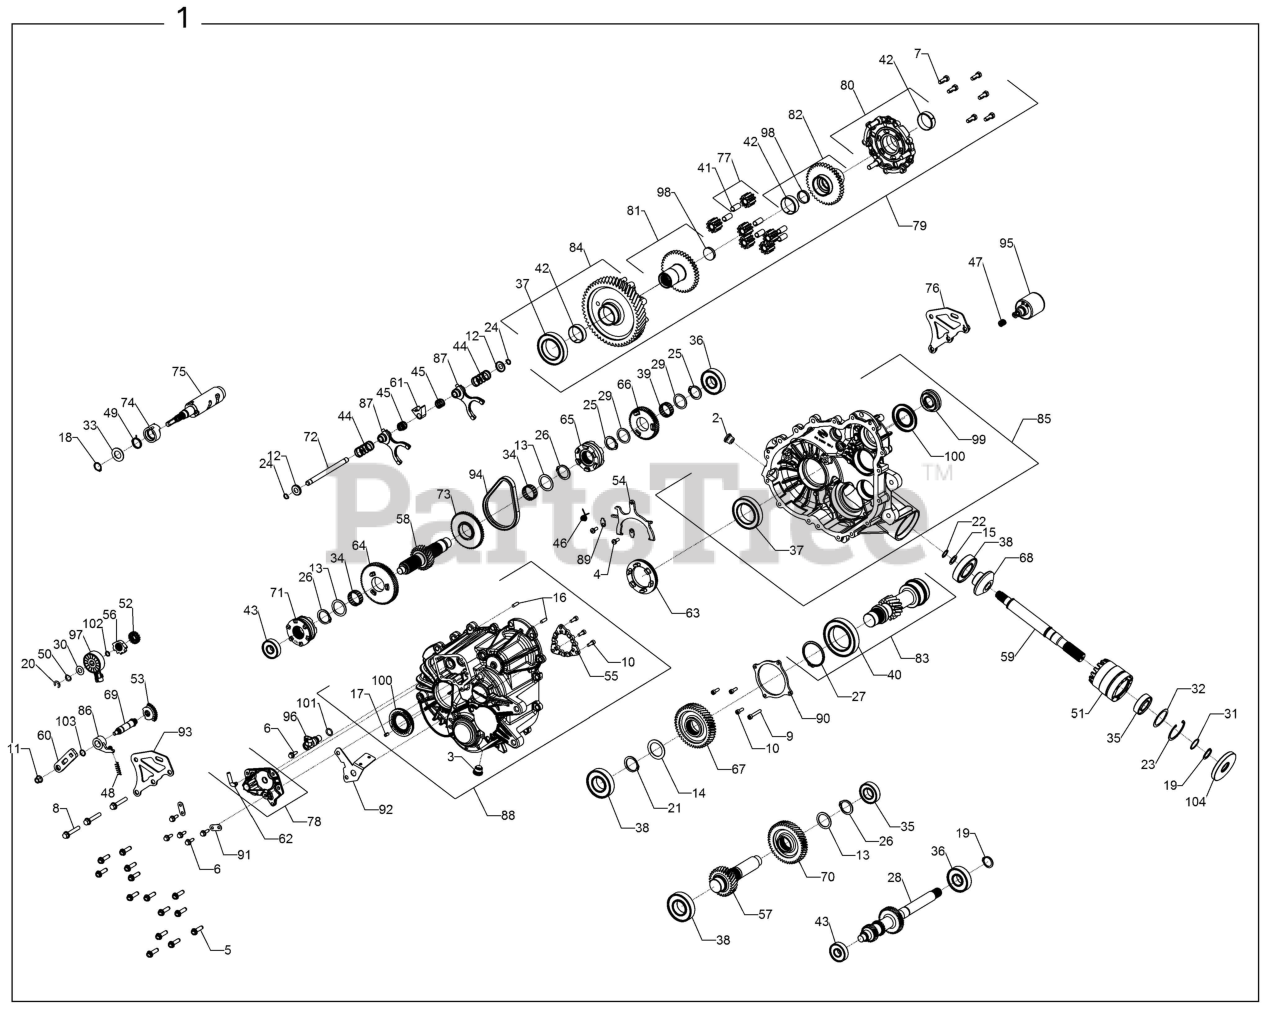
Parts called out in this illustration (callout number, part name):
1	ASM., MAIN GEARCASE
2	PLUG-SKT HD 1SO 6149,M18 X 1.5
3	PLUG-SOCKET HEAD W/MAG,M18X1.5
4	SCREW, TORX PAN HD M6 X 1 X 16
5	SCREW-HEXFLANGEHEAD,M8X1.25X30
7	SCREW-CAP HH,M8 X 1.25 X 20
9	SCR-M6X1.0X40,SOC/CAP(105344)
10	SCR-SCKT HD,CP,M6X1X18(105355)
11	NUT-M8X1.25,HXFLG,NYLN(110093)
12	WASHER-CUP
16	PIN, DOWEL, 6 X 20
17	SPRING-SLOTTED PIN,6MM
18	RING, RETAINING BASIC EXTERNAL
19	RING, SNAP
20	RING-RETAINING
21	RING,RETAINING
22	RING,RETAINING,EXTERNAL SHR-66
23	RING,RETAININGBASICINTRNL2.047
24	RING-RETAINING
25	RING,RETAINING
26	RING, RETAINING, EXTERNAL
27	RING, RETAINING
28	SHAFT-PINNION,INPUT,BOSS,LW
29	WASHER,THRUST
30	WASHER,THRUST,.446X.88X.025
31	SHIM 1.180 X .995
32	SHIM 2.040 OD X 1.630 ID
33	SPACER, 19.4 X 34 X 2
34	BEARING,NEEDLE
37	BEARING, BALL
38	BEARING-BALL
39	BEARING,NEEDLE
40	BEARING, BALL
41	BEARING,PLAIN,10X12X25
42	PLAIN,BEARING 40X44X15
43	BEARING, BALL
44	SPRING-COMPRESSION
45	SPRING-COMPRESSION
46	SPRING, TORSION RETURN
47	SPRING,COMPRSSN.54ODX.44IDX.05
48	SPRING, COMPRESSION DETENT
49	SPRING, TORSION
50	WASHER-SPRING,210393
51	TUBE, SNORKLE MACH
52	GEAR-SECTOR,16T
53	GEAR-SECTOR,31T-CUT TO 11T
54	SHIFT FORK (270507)
55	PARK PLATE (270509)
56	STAR, DETENT
57	SHAFT, IDLER, 29T
58	SHAFT,REVERSE,25T (285878)
59	SHAFT-FRONT OUTPUT(285914)
60	BELLCRANK
61	COLLAR-SHIFT
62	TUBE-VENT,90-1/4" HOSE
63	DOG-ENGAGEMENT
64	GEAR-LOW,67T(352856)
65	DOG, ENGAGEMENT, 6-FACE
66	GEAR, 53T
67	GEAR, 46T, STAGE 3
68	GEAR-13T,FRONT OUTPUT(352957)
69	SHAFT, SHIFT
70	GEAR,48T STAGE 2 (353115)
71	SHIFT DOG, PARK/LOW (353357)
72	RAIL-SHIFT SHAFT(353622)
73	SPROCKET, 48T, 6-FACE
74	PARK CAM
75	DRUM, SHIFT MACH
76	WELD-REAR MOUNT BRKT
77	GEAR SUBASSEMBLY
78	SUBASSY COVER, SECTOR GEARS
79	DIFF-LOCKING (411600)
80	SUBASSY-COVER,DIFF (411601)
81	SUBASSY-GEAR,39T SIDE (411607)
82	SUBASSY-GEAR,39T SIDE (411608)
83	ASM-SUB,PINION SHAFT(411759)
84	SUBASSY-GEAR,53T (411797)
85	SUBASSY,LH CASE(411919)
86	ROLLER PAWL
87	SUBASSEMBLY, SHIFT FORK
88	SUBASSEMBLY RH COVER
89	RETAINER-FORK
90	COVER, BEARING, CENTER DRIVE
91	BRKT-MOUNT(430592)
92	BRKT-MNT,HARNESS
93	BRKT-REAR MOUNT
94	CHAIN, SILENT
95	SOLENOID
96	SENSOR-SPEED,TRANS
97	SWITCH, ROTARY 2 PIN RESISTIVE
98	PLUG,EXPANSION,1 1/4
100	SEAL-TRIPLE LIP,VITON,40X70X7
101	O-RING, -113
104	SEAL-TRIPLE LIP 25X80X10
